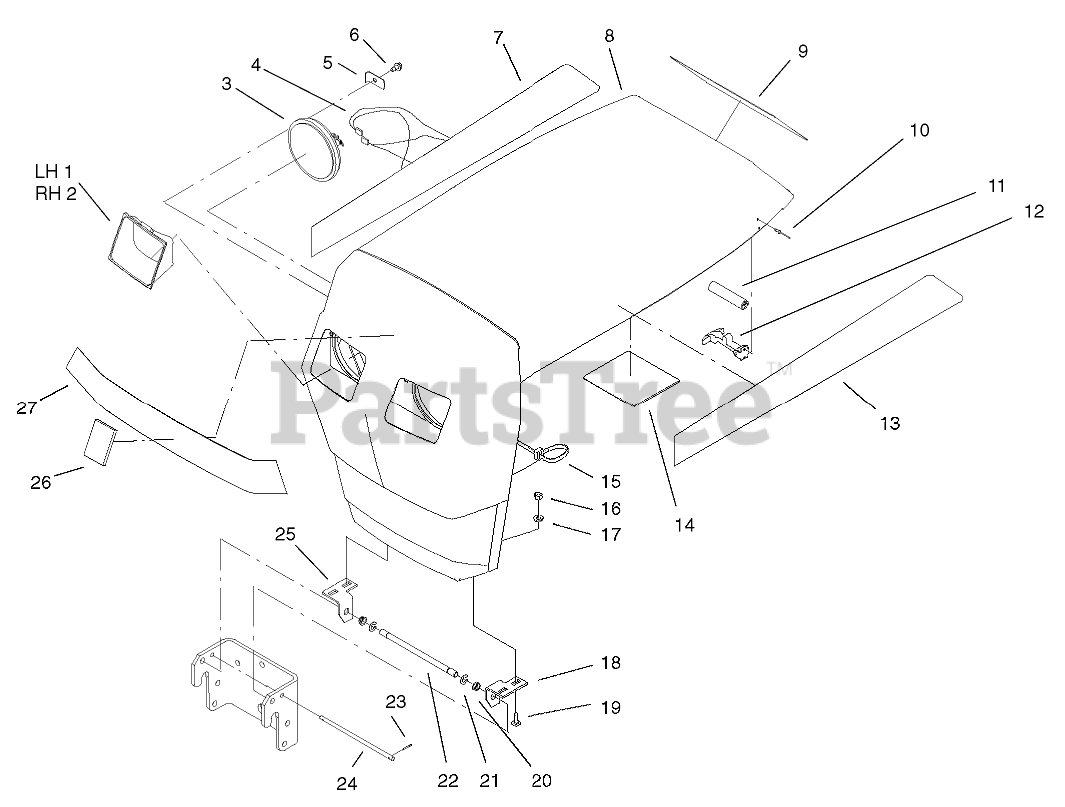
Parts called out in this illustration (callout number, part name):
1	BEZEL-HEADLIGHT, LH
2	BEZEL-HEADLIGHT, RH
3	HEADLAMP
4	HARNESS-HEADLIGHT
5	LOCK-HEADLIGHT
6	SCREW-HWH
7	DECAL - RH HOOD TOP
8	Hood
9	DECAL-DANGER, HOOD
10	RIVET-POP
11	EDGING-CONSOLE
12	HANDLE ASM
13	DECAL - LH HOOD TOP
14	Decal-Maintenance Classic
15	TIE-CABLE
16	NUT-LOCK, NI
17	WASHER-FLAT
18	BRACKET-GRILL, LH
19	SCREW-CARR
20	BUSHING-NYLINER
21	RING-RETAINING
22	ROD-GRILL PIVOT
23	PIN-COTTER
24	ROD-HOOD STOP
25	BRACKET-GRILL, R H
26	LOGO - HORSEHEAD
27	DECAL-FRONT HOOD, TOP
